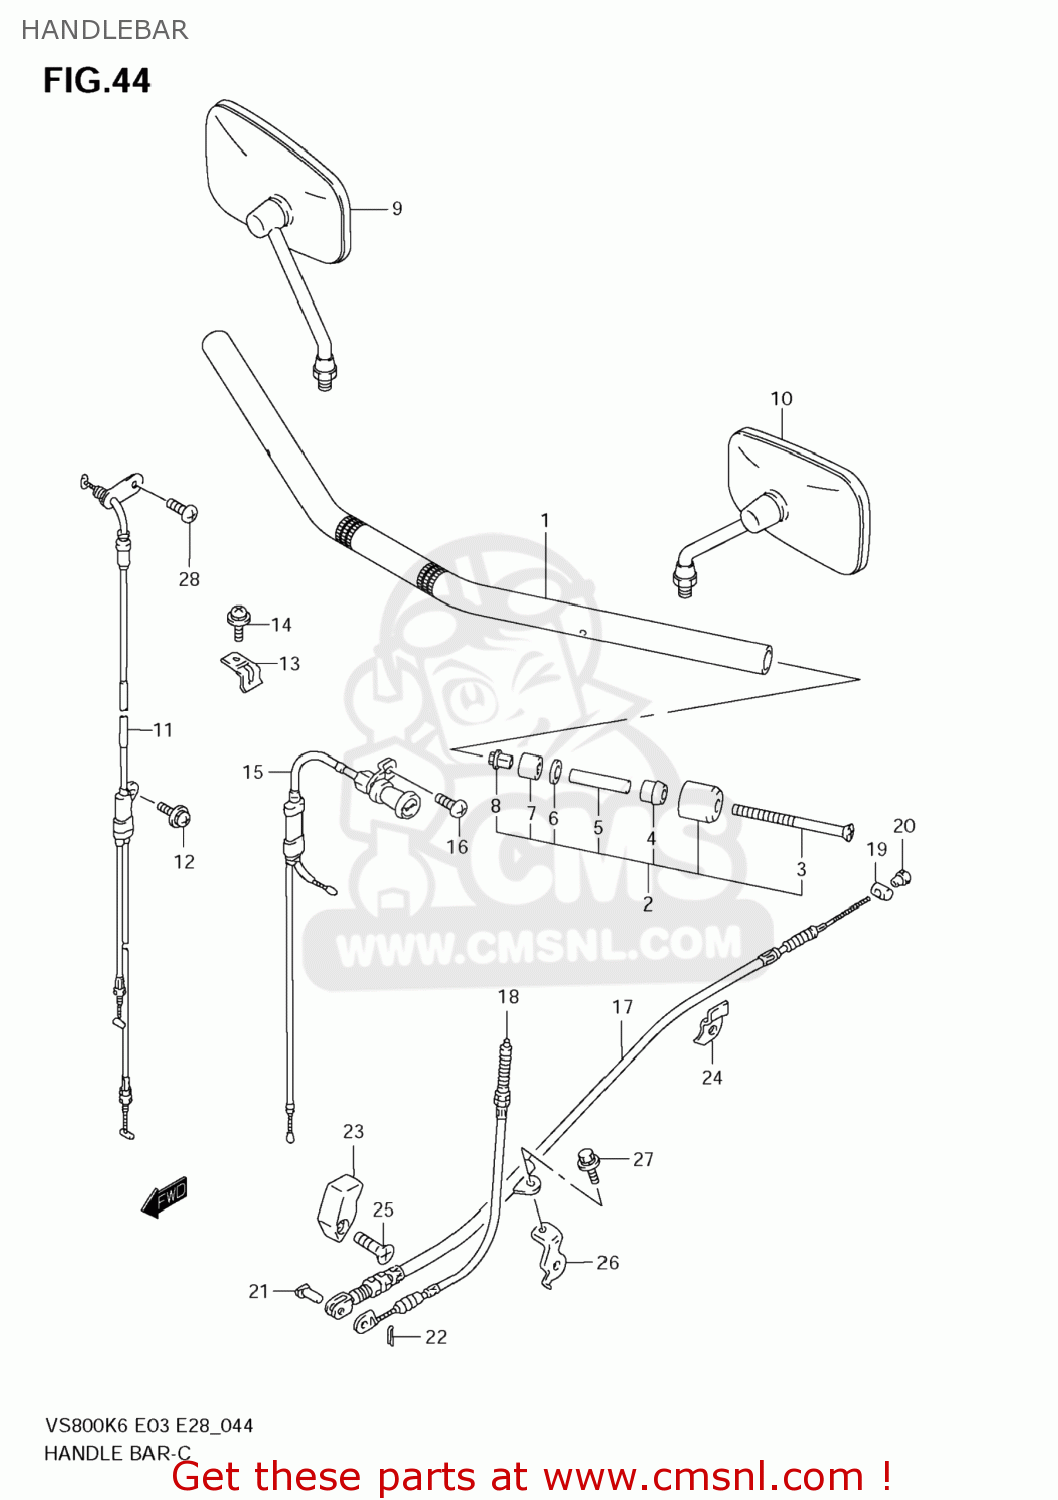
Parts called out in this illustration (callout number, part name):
1	HANDLEBAR
2	BALANCER SET,HANDLEBAR
3	SCREW(6X110)
4	EXPANDER,HANDLE BALANCER NO.2
5	SPACER,EXPANDER
6	WASHER(6.5X16X4)
7	EXPANDER,HANDLE BALANCER
8	NUT,HANDLE BALANCER
9	MIRROR ASSY,RR VIEW,R
10	MIRROR ASSY,RH
11	CABLE ASSY,THROTTLE
12	SCREW
13	CLAMP,THROTTLE CABLE
14	SCREW
15	CABLE ASSY,STARTER
16	SCREW
17	CABLE,RR BRAKE
18	CABLE,STOP LAMP SWITCH
19	PIN(13X18)
20	NUT
21	PIN(L:17.5)
22	PIN
23	GUIDE,RR BRAKE CABLE
24	CLAMP,RR BRAKE CABLE
25	SCREW
26	BRACKET,RR BRAKE CABLE
27	BOLT
28	SCREW(5X10)
